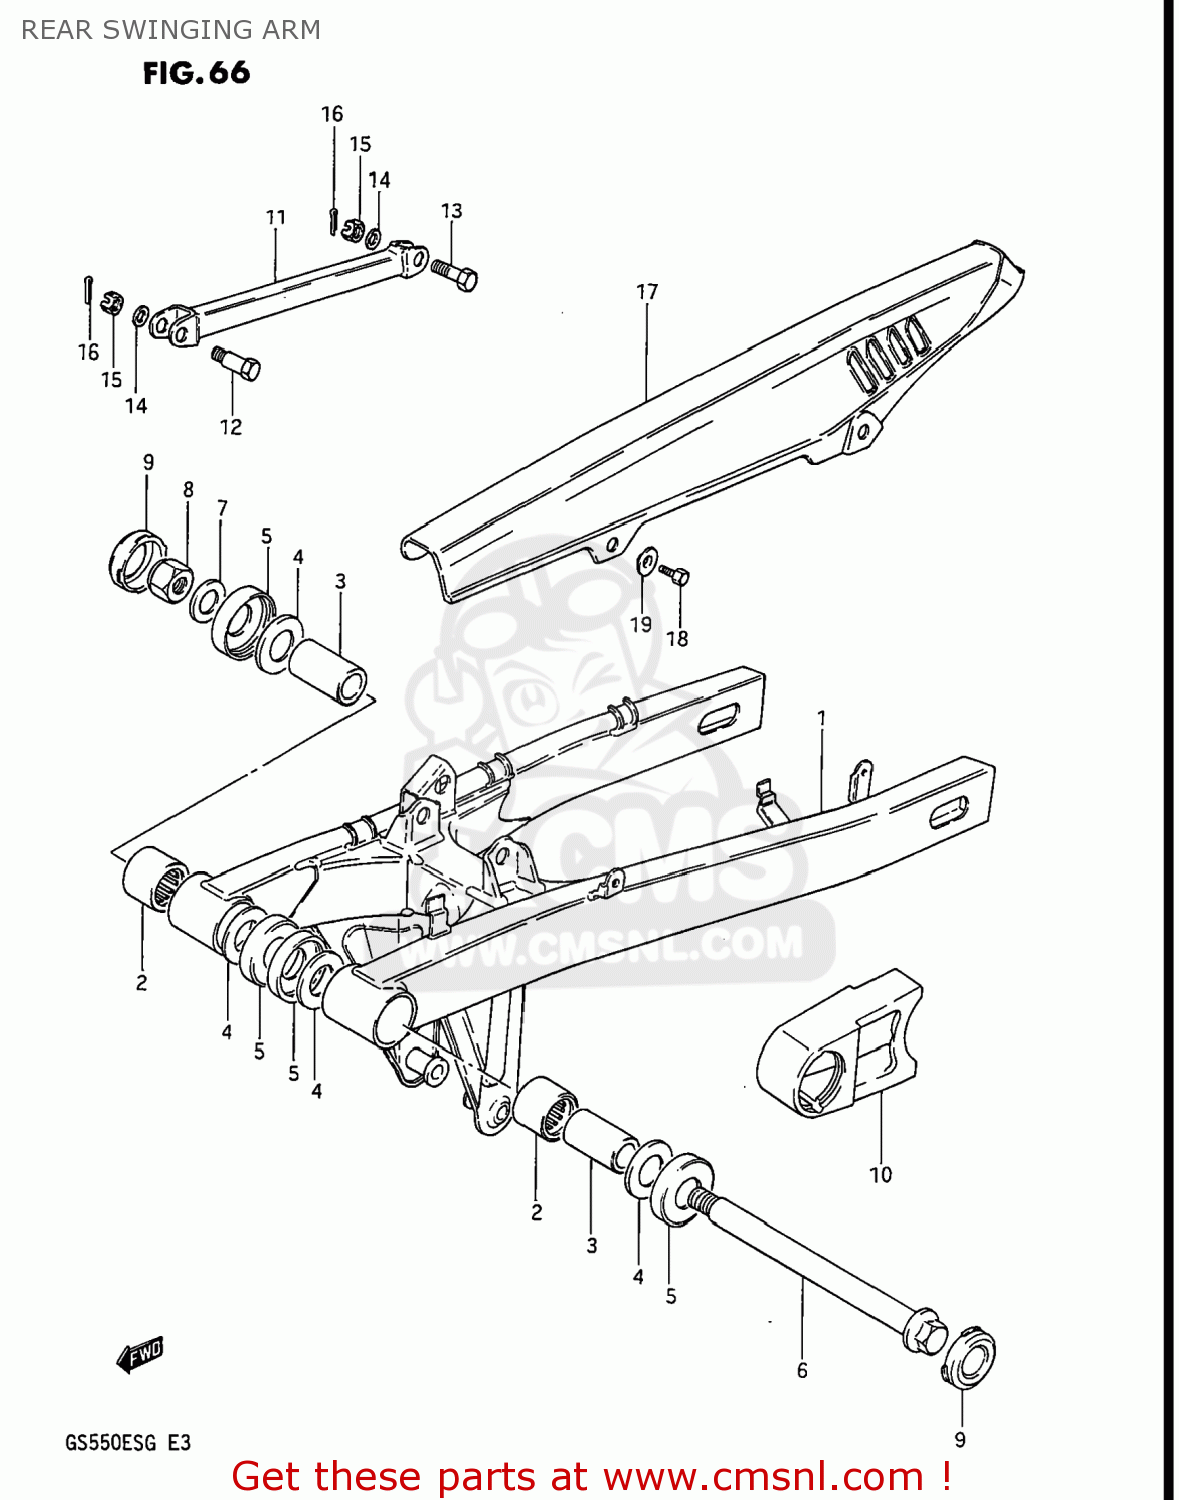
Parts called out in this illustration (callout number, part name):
1	ARM,REAR SWING
2	BEARING(25X33X30)
3	SPACER,RR SWGARM PIVOT
4	WASHER
5	COVER,RR SWGARM DUST SEAL
6	SHAFT,REAR SWING ARM
7	WASHER
8	NUT
9	CAP,SWINGINGARM PIVOT
10	BUFFER,DEFENSE
11	TORQUE LINK,REAR
12	BOLT
13	BOLT
14	WASHER 10MM
15	NUT
16	PIN 20X20
17	CASE,CHAIN
18	BOLT
19	WASHER
